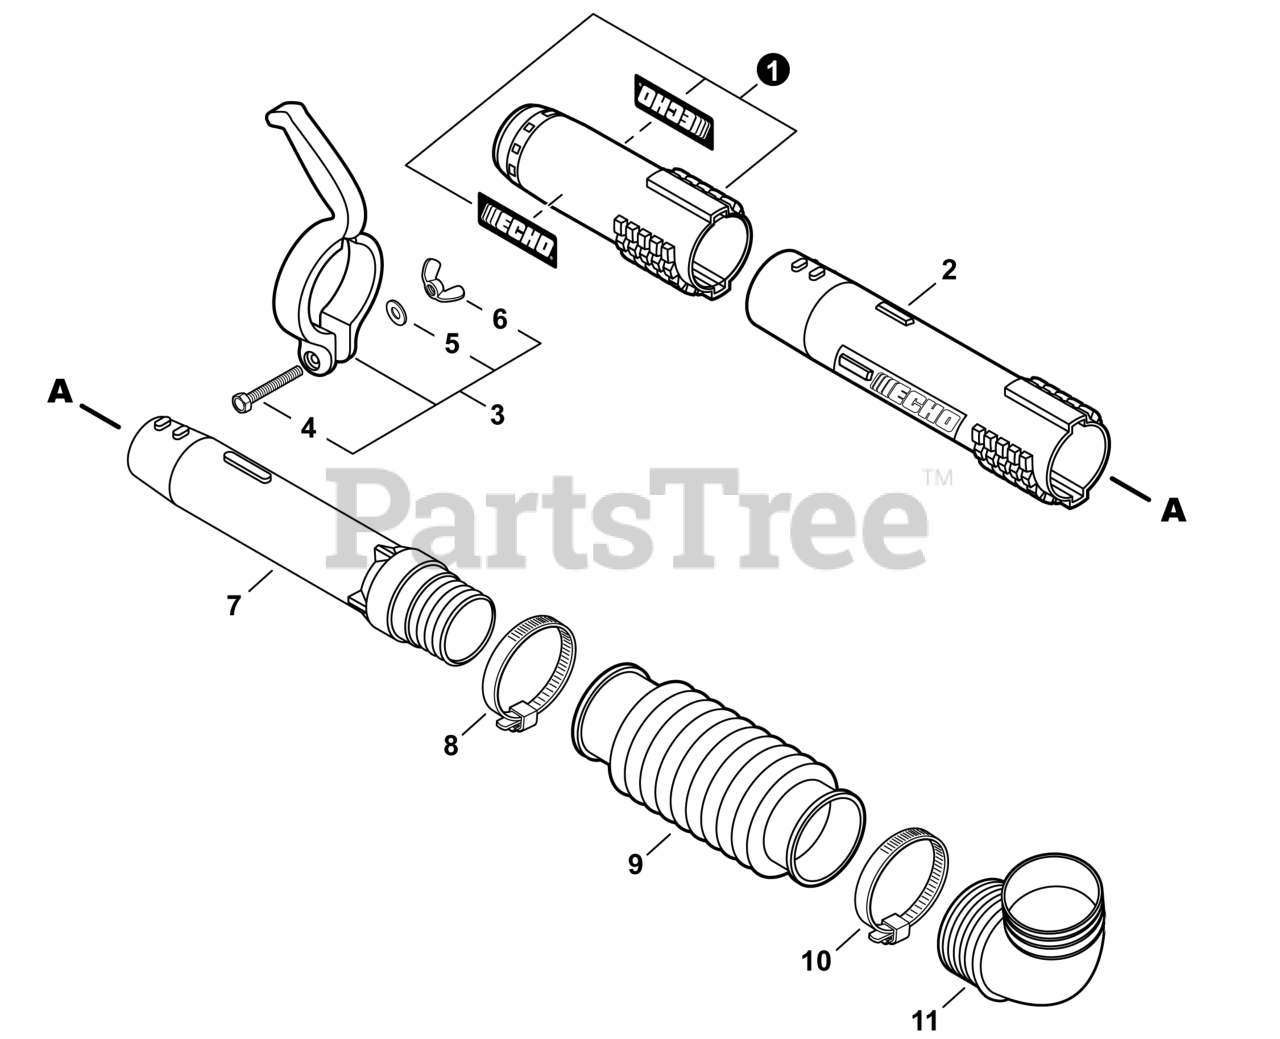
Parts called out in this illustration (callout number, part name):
1	TUBE SET, BLOWER - NOZZLE
2	TUBE, BLOWER - STRAIGHT
3	HANDLE SET, FRONT
4	BOLT 6x45
5	WASHER 6.5x11.5x0.8
6	NUT, WING 6
7	TUBE, BLOWER - SWIVEL
8	CLAMP - BAND 58.7 MM / 82.5 MM
9	TUBE, BLOWER - FLEXIBLE
10	CLAMP - BAND 78 MM / 103 MM
11	TUBE, BLOWER - ELBOW
